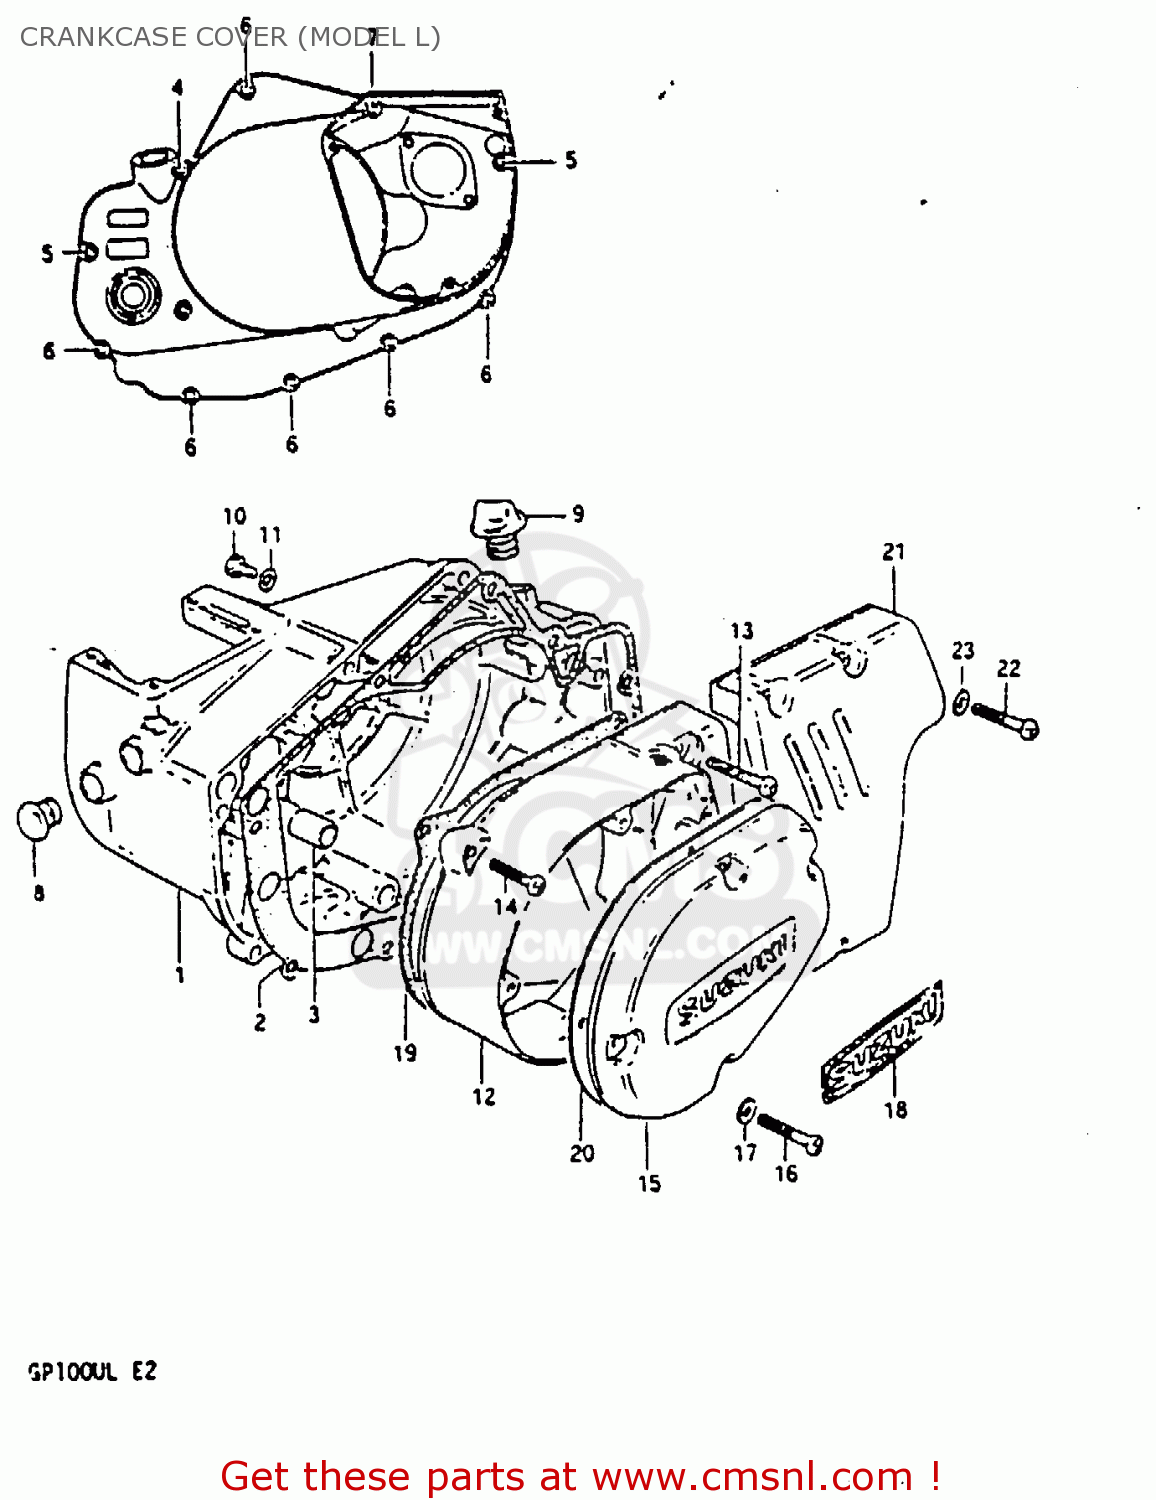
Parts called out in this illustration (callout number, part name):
1	COVER, CLUTCH (BLACK)
2	GASKET, CLUTCH COVER (MCA)
3	PIN
4	SCREW
5	SCREW
6	SCREW
7	SCREW
8	Plug
9	PLUG SET
10	SCREW(6X10)
11	GASKET(6.2X11X1) (NAS)
12	COVER, MAGNETO (BLACK)
13	SCREW
14	SCREW
15	CAP, MAGNETO INSPECTION (BLACK)
16	SCREW
17	WASHER,5MM
18	EMBLEM,MAG INSPECTION CAP
19	GASKET, MAGNETO COVER
20	GASKET,MAGNETO INSPECTION CAP (NAS)
21	COVER, ENGINE SPROCKET (BLACK)
22	SCREW
23	WASHER
